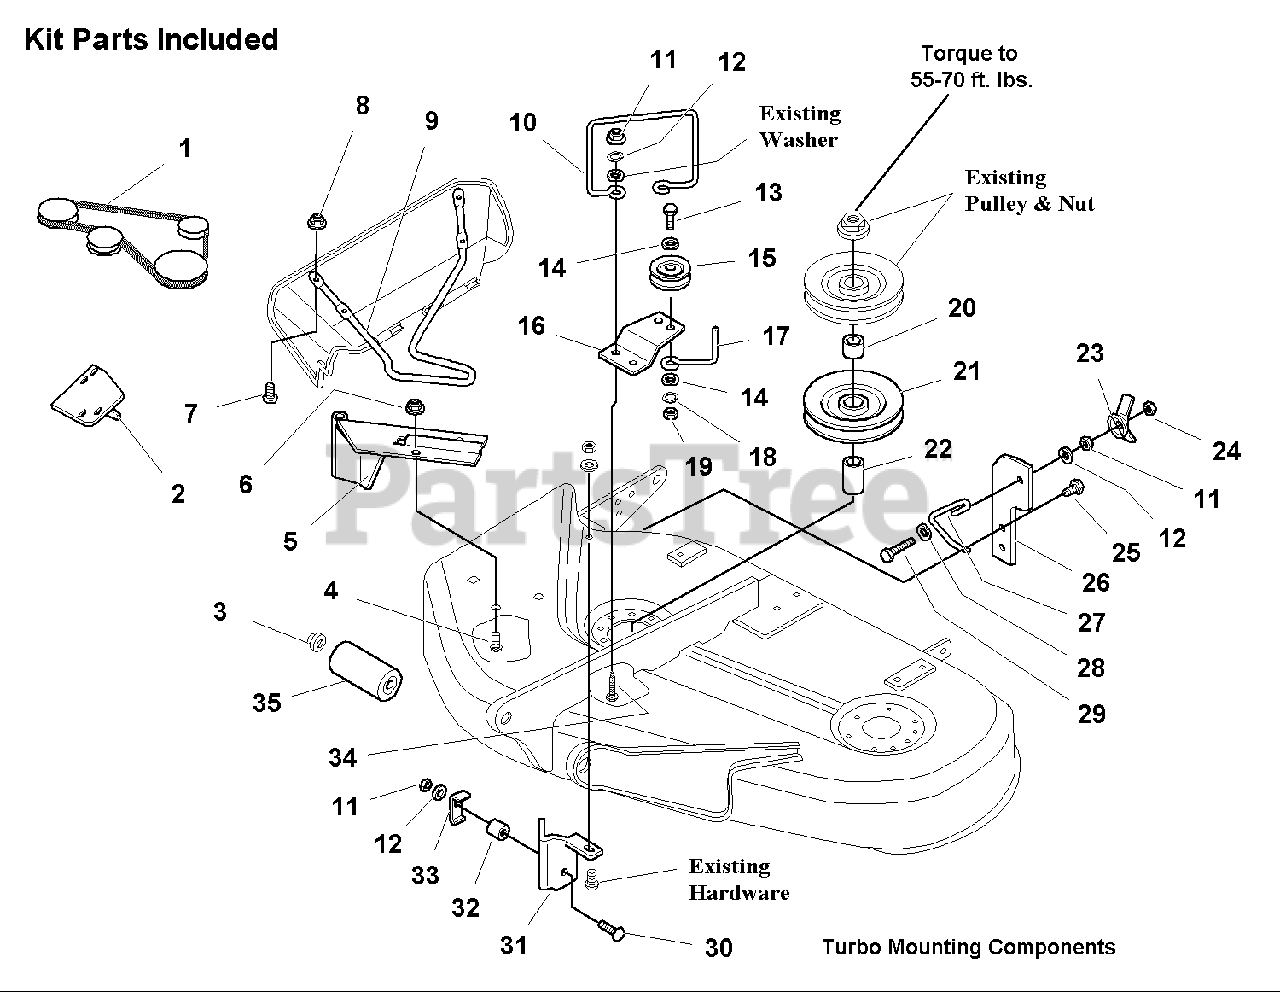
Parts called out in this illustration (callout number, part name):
2	MOUNTING BRACKET
3	PAL NUT, 5/8
4	CARRIAGE BOLT, 5/16-18 x 3/4
5	PIVOT ASSY.
6	NUT, Hex, Flange, Whizlock, 5/16-18
7	SCREW, Truss Hd., #10-24 x 3/4
8	NUT, Nylock, #10-24
9	ROD, Deflector
10	BELT GUIDE, Turbo
11	NUT, Hex, 5/16-18
12	LOCKWASHER, 5/16
13	CAPSCREW, 3/8-16 x 1-1/4
14	WASHER, Flat, 3/8
15	IDLER PULLEY, 2-3/4 OD
16	BRACKET, Idler
18	LOCKWASHER, 3/8
19	NUT, Hex, 3/8-16
20	SPACER, Short, Splined
21	PULLEY ASSEMBLY, 5" OD
22	SPACER, Long
23	NUT, Wing Assy, 5/16
24	NUT, Hex, Center Lock, 5/16-18
25	SCREW, Taptite, 5/16-18 x 1/2
26	BRACE,
27	SPRING LATCH
28	WASHER, Flat
29	CAPSCREW, Hex Hd, 5/16-18 x 2-1/2
30	CARRIAGE BOLT, 5/16-18 x 1-1/4
31	BRACKET ASSY.,
33	BRACKET,"L"
34	SCREW, Taptite, 5/16-18 x 1-1/2
